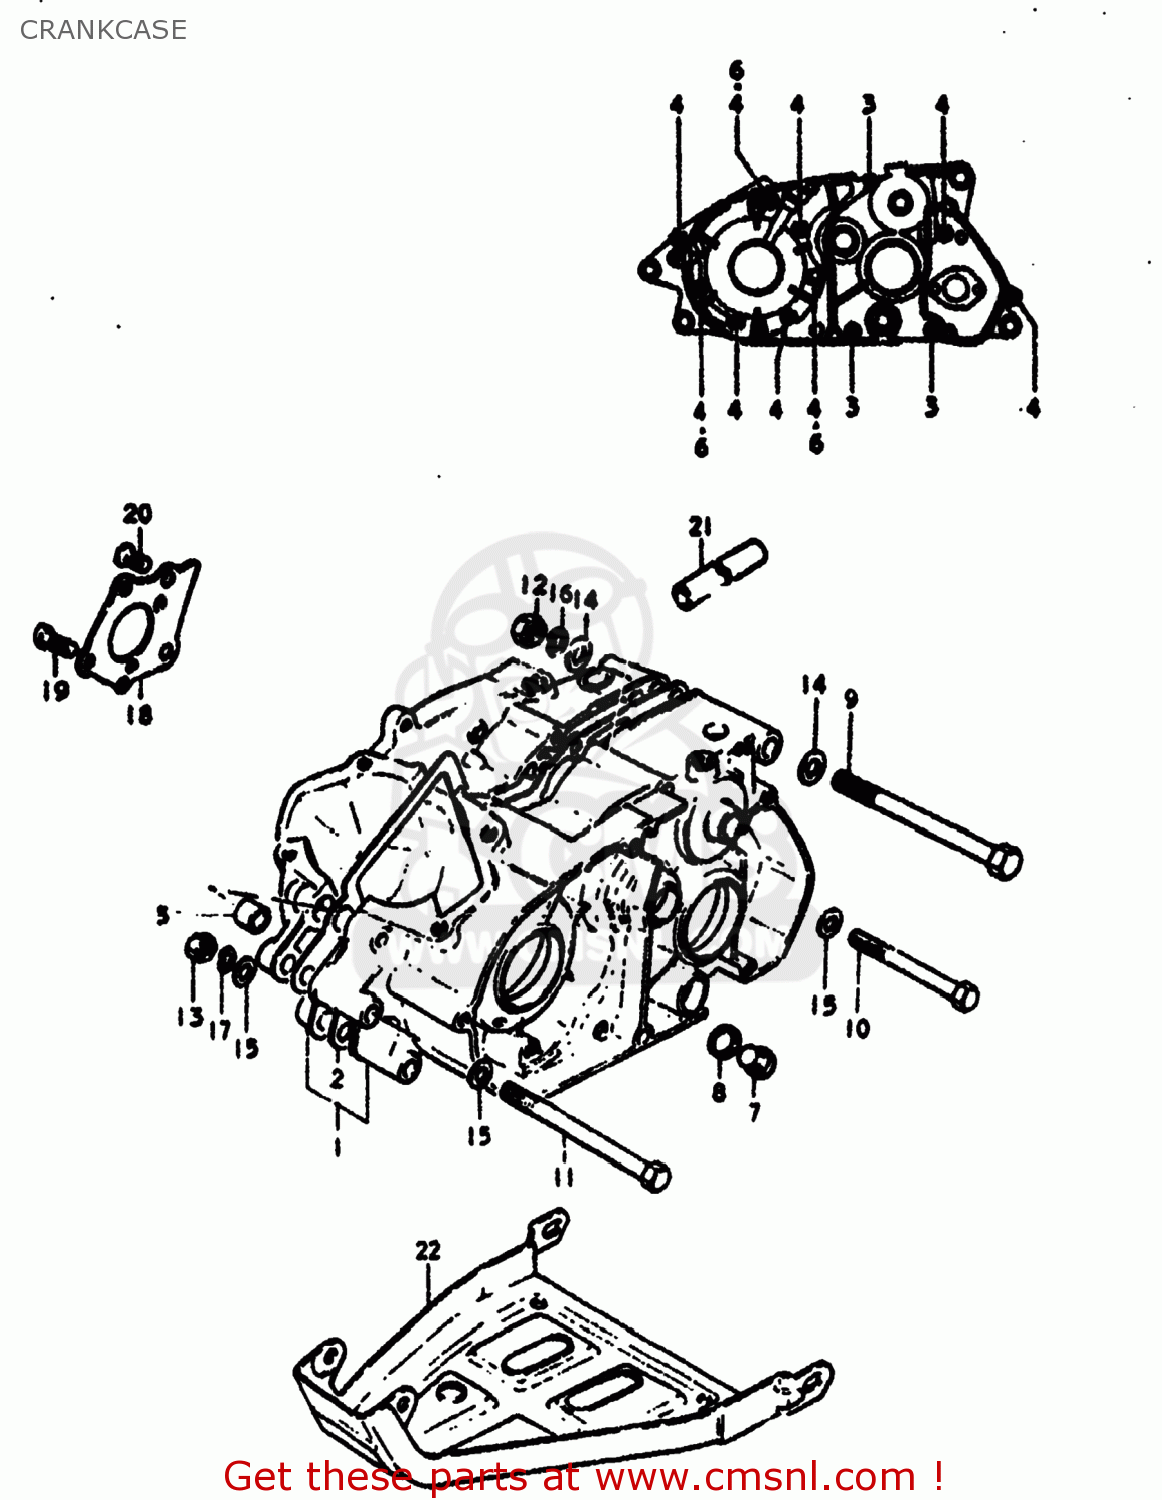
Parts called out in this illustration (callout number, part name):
1	CRANKCASE SET
2	GASKET,CRANKCASE (MCA)
3	SCREW
4	SCREW (6X45)
5	PIN
6	WASHER 6MM
7	PLUG
8	GASKET(14X19.2X2) (NAS)
9	BOLT 10X120
10	HEXAGON BOLT 8X80
11	BOLT 8X110
12	NUT
13	NUT
14	WASHER
15	WASHER
16	LOCK WASHER
17	LOCK WASHER
18	PLATE,OIL RESERVOIR
19	SCREW
20	SCREW
21	HOSE
22	GROMMET
